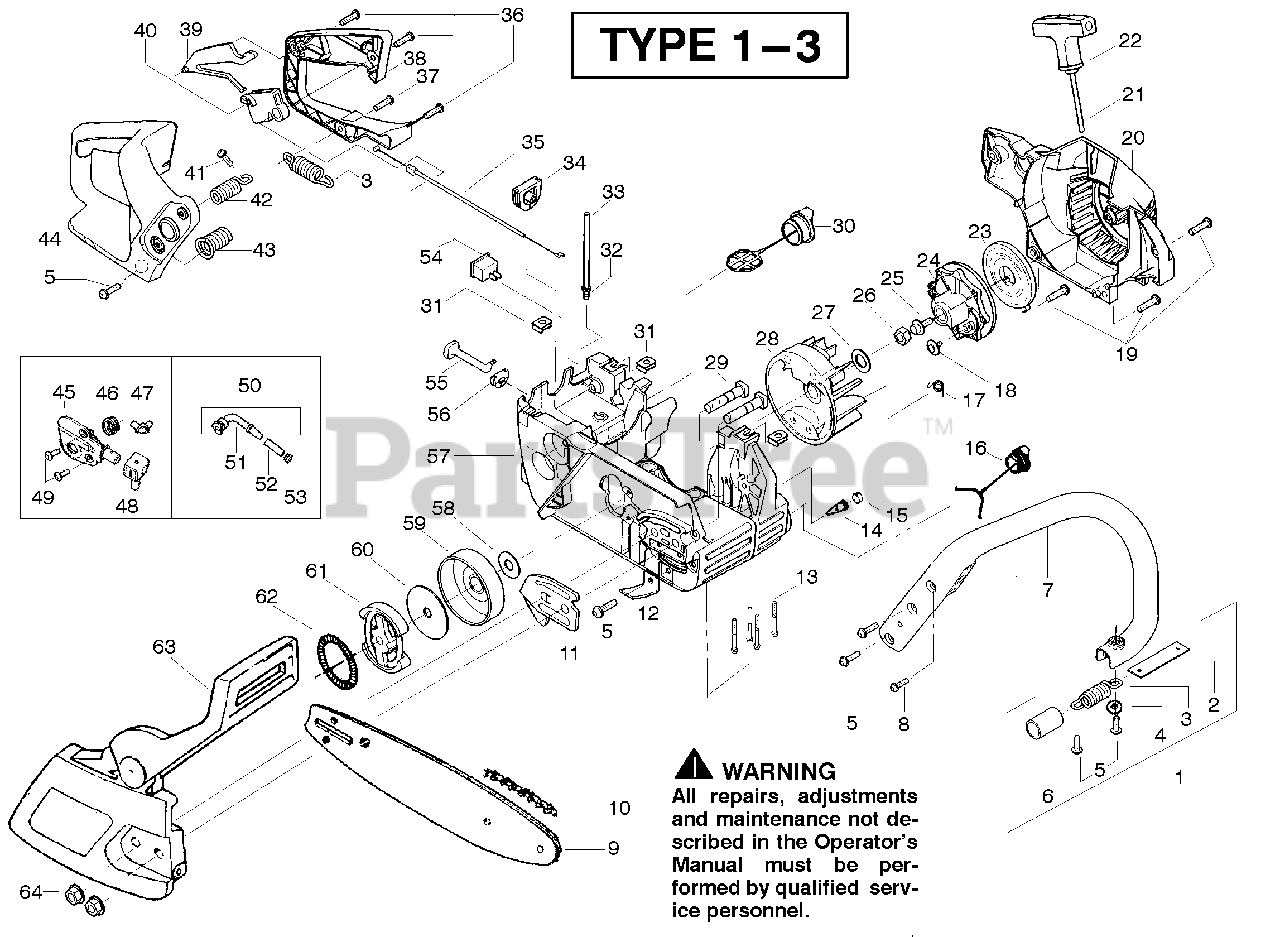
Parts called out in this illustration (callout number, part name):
1	Assy.- Isolator
2	Limiter Strap
3	Spring- Isolator
6	Sleeve-AV Spring
7	Front Handle
9	Bar (16" Quick Adjust)
9	Bar (16" Pro Lam Quick Adj.)
10	Chain-16"
11	Plate-Bar Mounting
12	Chain Catcher
14	Check Valve
15	Plug-Bronze Vent
16	Oil Cap Ass'y.
17	Spring-Starter Dog
20	Fan Housing
21	Rope Kit
22	Starter Handle
23	Recoil Spring
24	Starter Pulley
26	Nut- Flywheel
27	Washer- Flywheel
28	Flywheel Ass'y.
29	Bolt - Bar
30	Fuel Cap Ass'y.
31	Nut - "U"-Type
32	Fitting - Fuel Line
33	Kit-Line purge/tank (large dia.)
34	Grommet-Cable
35	Cable-Throttle
38	Cover-Rear Handle
39	Throttle lockout
40	Throttle trigger
42	Isolator Assy. (Upper)
43	Isolator Assy. (Lower)
44	Rear Handle
45	Oil Pump Kit
46	Gear-Worm Spring
47	Elbow-Oil Pickup
48	Seal Block
50	Oil Pick-up Ass'y
51	Pick-up Oiler
52	Oil Filter
53	Plug-Oil Filter
54	Kit - Switch
55	Knob - Choke
56	Grommet-Choke knob
57	Assy. - Chassis
58	Washer - thrust
59	Clutch drum assy- with bearing
60	Washer - Clutch
61	Assy. Clutch
62	Spring - Clutch
63	Kit - Chain Brake
64	Nut-Bar Mounting
